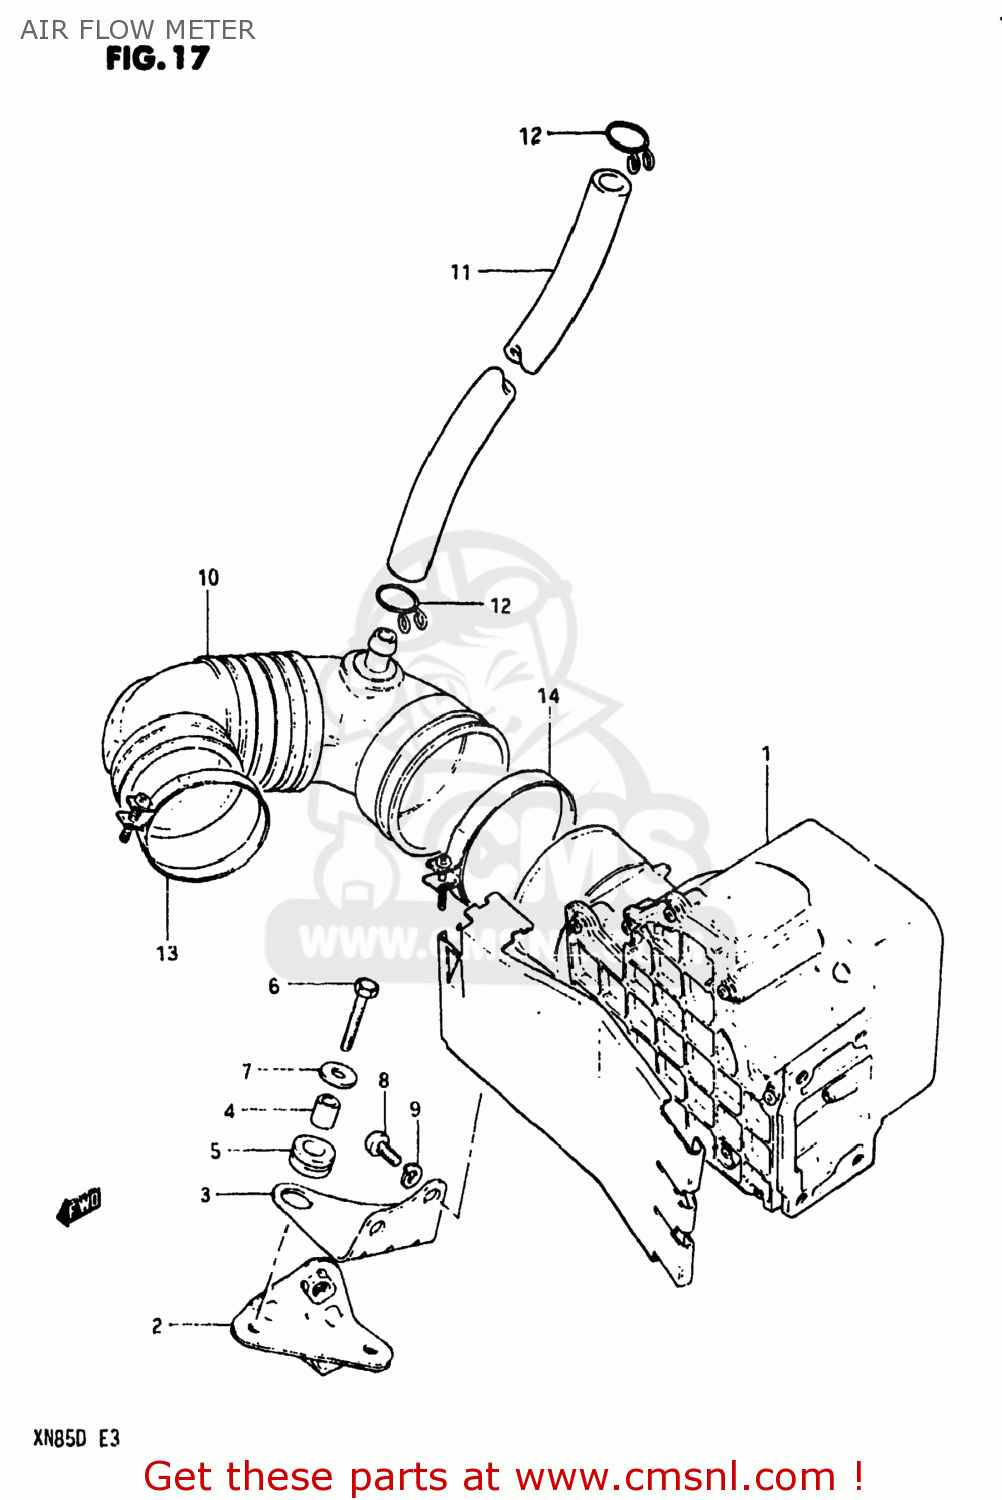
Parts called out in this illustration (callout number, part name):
1	METER ASSEMBLY,AIR FLOW
2	BRACKET (1)
3	BRACKET (2)
4	SPACER (6.8X10X10)
5	CUSHION
6	BOLT
7	WASHER
8	SCREW 6X12
9	LOCK WASHER
10	HOSE ASSY, AIR FLOW METER
11	TUBE,BREATHER
12	CLIP
13	CLAMP
14	CLAMP
